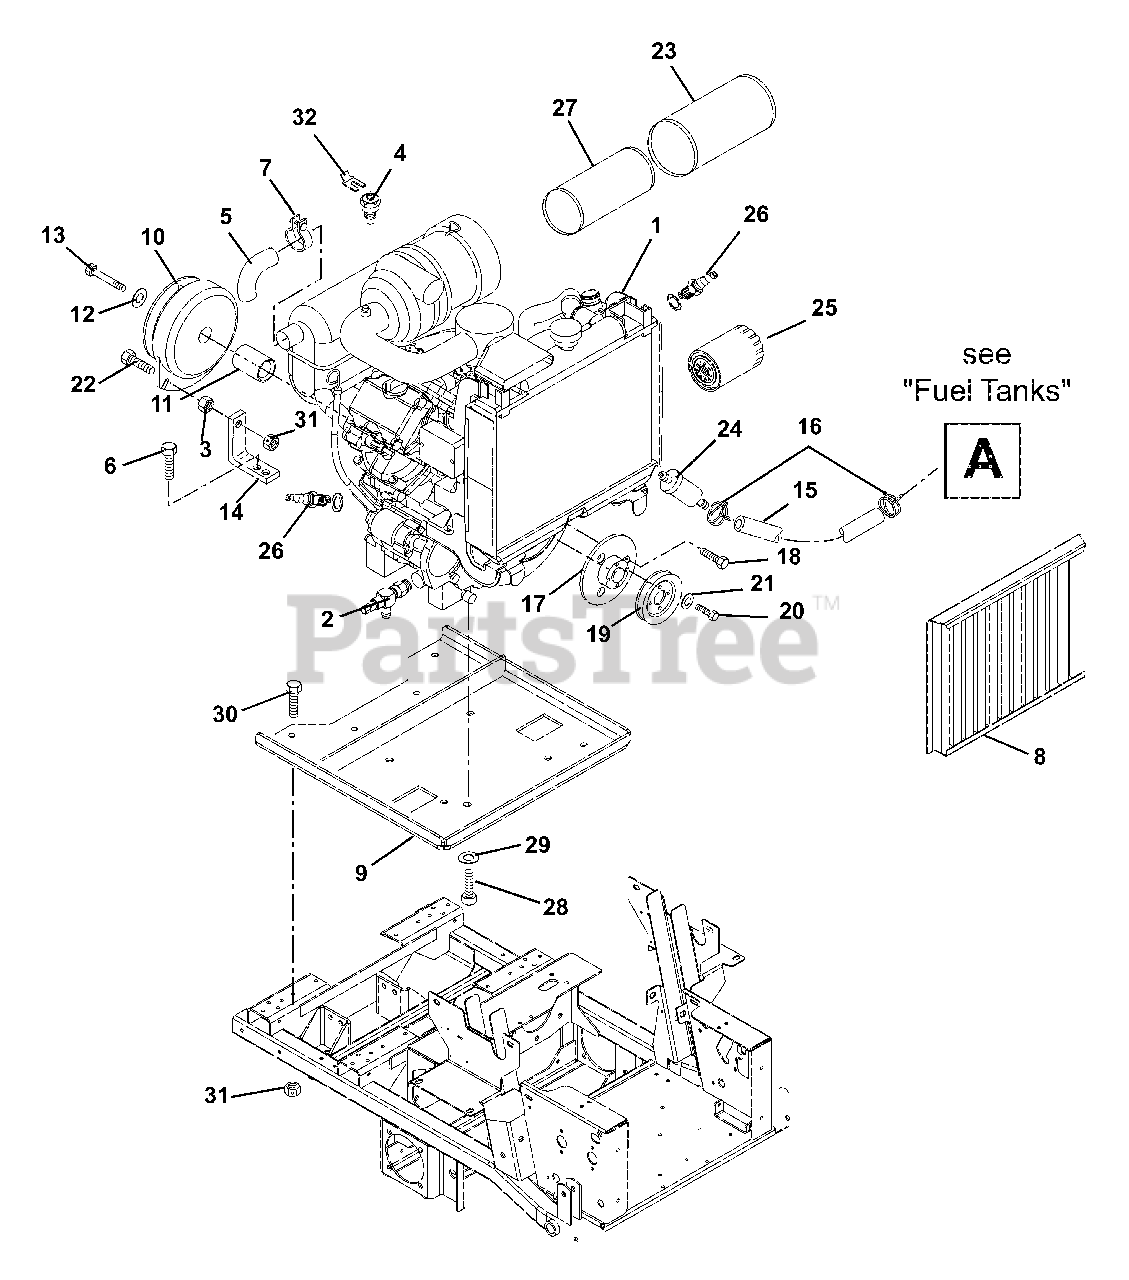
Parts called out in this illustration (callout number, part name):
1	Engine, 27HP Gas Kawasaki
2	Drain, Oil
3	Nut, Jam .312-18
4	Temperature Sender
6	Screw, Tapping .38-16 x .75 Hex Washer Head
7	Clamp, Muffler Assembly
9	Weldment, Engine Plate
10	Clutch, Electric
11	Spacer, Clutch
12	Washer, Locking .44 x .109
13	Bolt, Hex M10 x 1.5 x 60 8.8
14	Anchor, Clutch
15	Gas Line, Bulk .25 ID
16	Clamp, Hose Wire .49/.51 x .116
17	Adapter, Sheave (Kawasaki)
18	Bolt, M8-1.25 x 25
19	Sheave, Poly-V 1.0 x 3.25
20	Bolt, Hex .25-20 x .50 Grade 5
21	Washer, Locking .25 x .062 Regular
22	Bolt, Hex .31-18 x 1.50 Grade 5
23	Air Filter
24	Fuel Filter
25	Oil Filter
26	Spark Plug
27	Element, Precleaner
28	Bolt, Hex M10 x 1.5 x 25
29	Washer, Locking .44 x .109 Regular
30	Bolt, Hex .31-18 x 1.00 Grade 5
31	Nut, Locking Top Flange .38-16
32	Terminal, Male Quick Connect
NS	Kit, Break Pole Module Replacement
